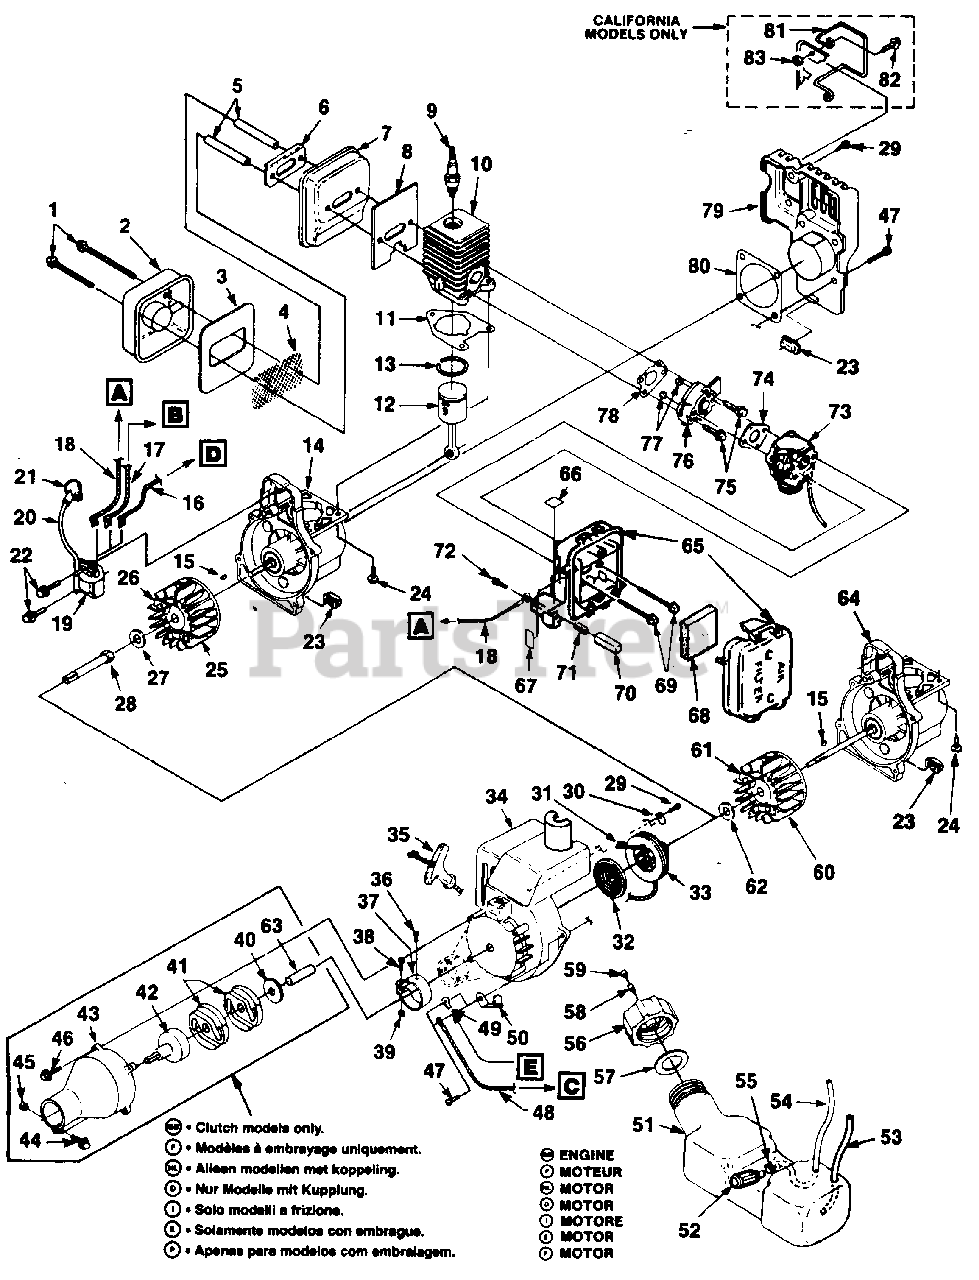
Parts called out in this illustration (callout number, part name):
1	SCREW- (10-24 x 2 1/2")
2	COVER- Muffler
3	BAFFLE- Muffler
4	SCREEN- Spark
5	SPACER- Muffler
6	PLATE- Reinforcing
7	BODY- Muffler
8	GASKET- Muffler
9	SPARK PLUG (DJ7Y)
10	CYLINDER & GASKET (ST-145,ST-155,ST-175BCST-175C,ST-175G,ST-185BC,ST-
11	GASKET- Cylinder
12	PISTON & ROD ASSEMBLY (ST-145,ST-155,ST-175BC,ST-175C,ST-175G,ST-185BC
13	RING- Piston
14	CRANKCASE (ST-145, ST-155, ST-175G, ST-275, GST, HGT)
15	KEY- Woodruff
16	LEAD- Electrical (ST-385BC, HBC-30, HBC-30B)
17	LEAD- Electrical (ST-175BC,ST-175C,ST-185BC,ST-285BC,HLT-17C,HBC-18)
18	LEAD- Electrical (ST-145,ST-155,ST-175G,ST-275,GST,HGT,HLT-16,HLT-28
19	MODULE- Ignition
20	LEAD- High-Tension
21	TERMINAL- High-Tension
22	SCREW- Taptite (8-32 x 1")
23	BUMPER- Rubber
24	SCREW- (10-24 x 3/4") (T-27)
25	ROTOR (ST-145, ST-155, ST-175G, ST-275, HGT, GST, HLT-16, HLT-28)
26	KIT- Starter pawl
27	WASHER- Flat (5/16") (ST-145,ST-155,ST-175GST-275,GST,HGT,HLT-16,HLT
28	CONNECTOR- Drive (ST-145, ST-155, ST-175G, ST-275, HLT-16, HLT-28)
29	SCREW- Plastite (10 x 1/2")
30	BRACKET- Retaining
31	ROPE- Starter (42")
32	SPRING & CONTAINER
33	PULLEY- Starter
34	HOUSING Engine (ST-175BC,ST-175C,ST-185BC,ST-285BC,ST-385BC,HLT-17C,H
35	GRIP- Starter
36	SCREW- Pan hd. (#10 x 3/8")
37	CLAMP
38	SCREW- Hex sems (10-24 x 3/8")
39	NUT- Square
40	WASHER- Clutch (ST-175BC,ST-175C,ST-185BC,ST-285BC,GST-BC,HLT-17C,HBC
41	CLUTCH (ST-175BC, ST-175C,ST-185BC,ST-285BC,ST-385BC,GST-BC,HLT-17C-UT
42	CONNECTOR & DRUM (ST-175BC,ST-175C,ST-185BC,ST-285BC,ST-85BC,GST-BC,H
43	TUBE ADAPTOR (ST-175BC,ST-175C,ST-185BC,ST-285BC,ST-385BC,GST-BC,HLT-
44	SCREW (10-24 x 1 1/4")
45	NUT (10-24)
46	SCREW (10-24 x 7/8")
47	SCREW- Taptite (10-24 x 3/4")
48	LEAD- Ground
49	TERMINAL
50	BRACKET- Cable
51	TANK- Fuel
52	FILTER- Fuel
53	TUBING- Rubber (8")
54	TUBING- Rubber (8")
55	CLAMP- Wire
56	FUEL CAP ASSEMBLY
57	GASKET- Fuel cap
58	VALVE- Duck bill
59	FILTER- Cap
60	ROTOR (ST-175BC,ST-175C,ST-185BC,ST-285BC,ST-385BC,GST-BC,HLT-17C-UT-
61	STARTER PAWL
63	SPACER
64	CRANKCASE (ST-175BC, ST-175C, ST-185BC, ST-285BC, ST-385BC, GST-BC)
65	AIR FILTER BOX
66	DECAL- Push-Hold
67	DECAL- Choke-Run
68	FILTER- Air
69	SCREW- (10-24 x 2 1/4")
70	BUTTON- Switch
71	SPRING- Compression
72	SCREW- Plastite (#6)
73	CARBURETOR (Walbro)
74	GASKET- Carburetor
75	SCREW- Taptite (10-24 x 1")
76	HEAT DAM
77	NUT (10-24)
78	GASKET- Heat dam
79	CRANKCASE COVER
80	GASKET- Crankcase cover
81	WIRE GUARD KIT
82	SCREW- Hex sems (10-24 x 1/2")
83	NUT (10-24)
